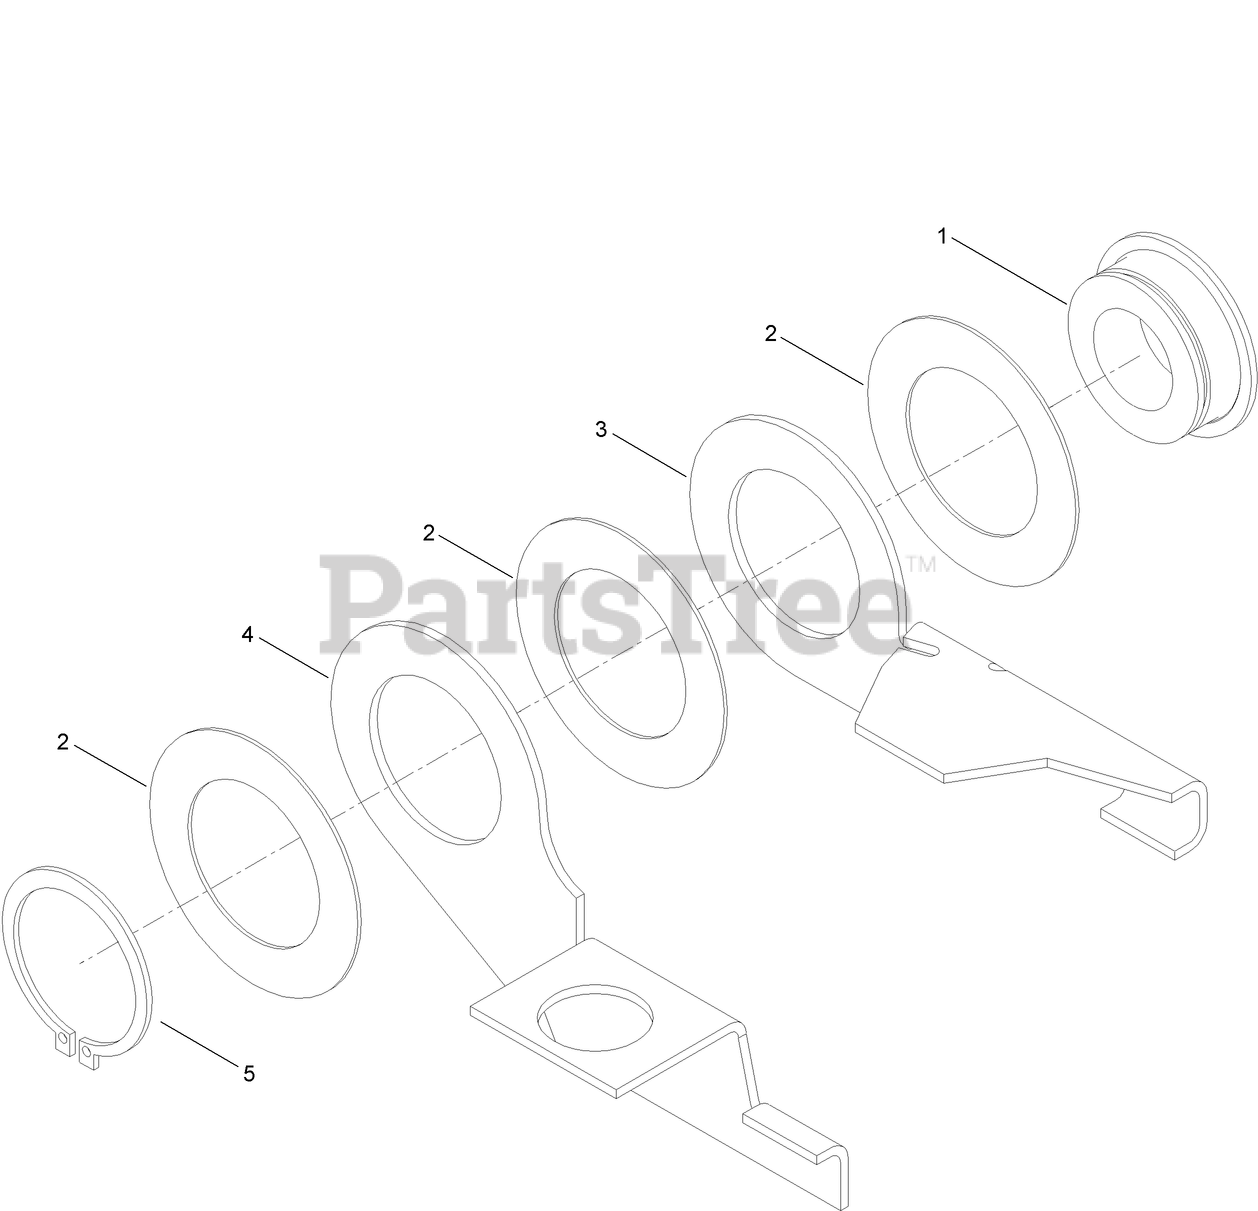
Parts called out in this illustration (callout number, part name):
3	PLATE-MOUNTING, SWITCH
4	PLATE-MOUNTING, SWITCH
5	RING-RETAINING
